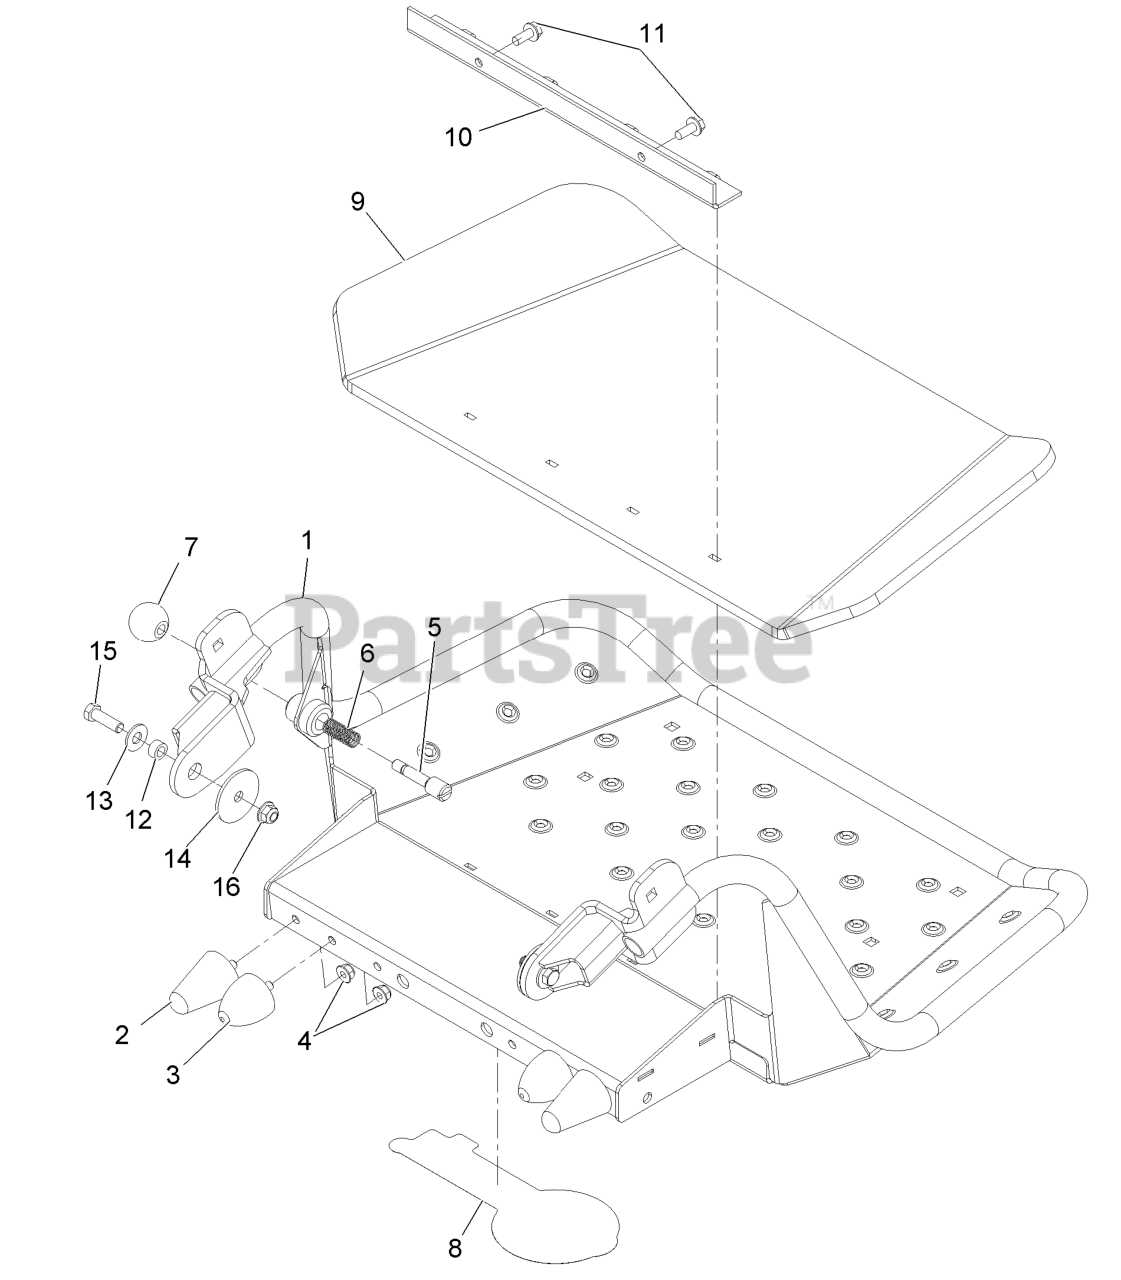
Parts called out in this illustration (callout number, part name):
2	BUMPER-RUBBER
3	BUMPER-RUBBER
4	NUT-HF, NI
5	PIN-LATCH
7	KNOB-BALL
8	DECAL, EXMARK LOGO
10	CLAMP-SHIELD
11	SCREW-THD ROLL, HWH
12	SPACER
13	WASHER-FLAT
14	WASHER-FLAT
15	SCREW-HH
16	NUT-HF, NI
